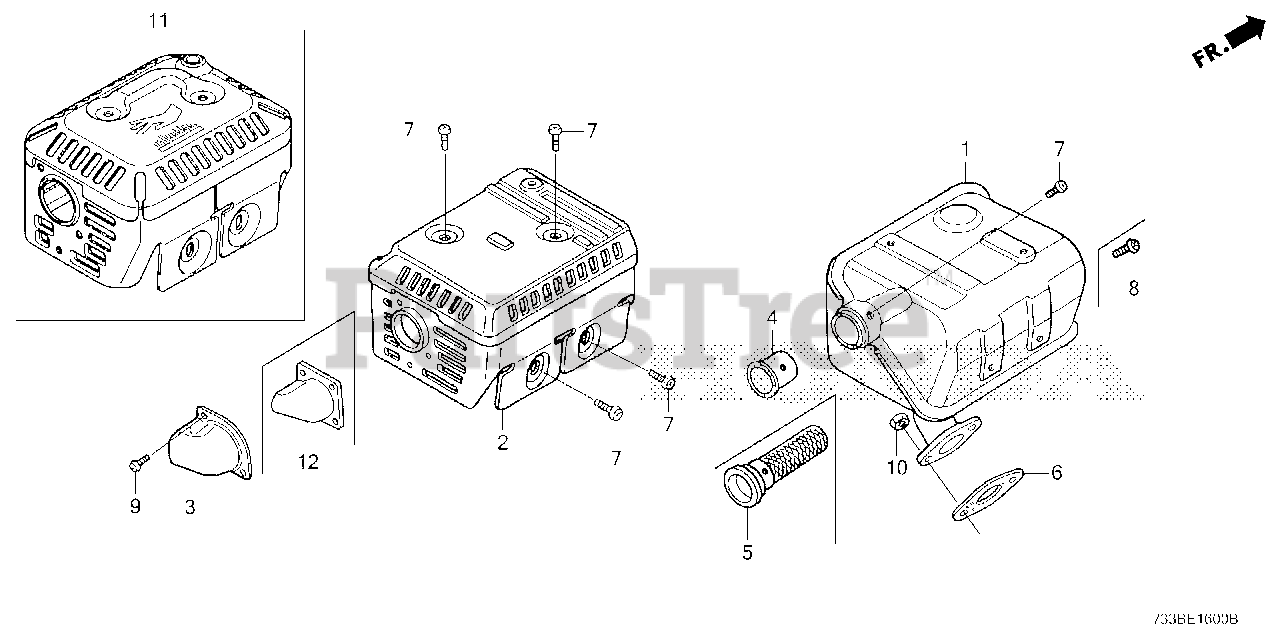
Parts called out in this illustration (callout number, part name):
1	MUFFLER (STD)
1	MUFFLER (ARRESTER)
2	PROTECTOR, MUFFLER (STD) (BLACK)
3	DEFLECTOR, MUFFLER
4	PIPE, TAIL
5	ARRESTER, SPARK
6	GASKET, MUFFLER
7	SCREW, TAPPING (5X8)
8	SCREW, TAPPING (4X6)
9	SCREW, TAPPING (4X6)
10	NUT, HEX. (8MM)
